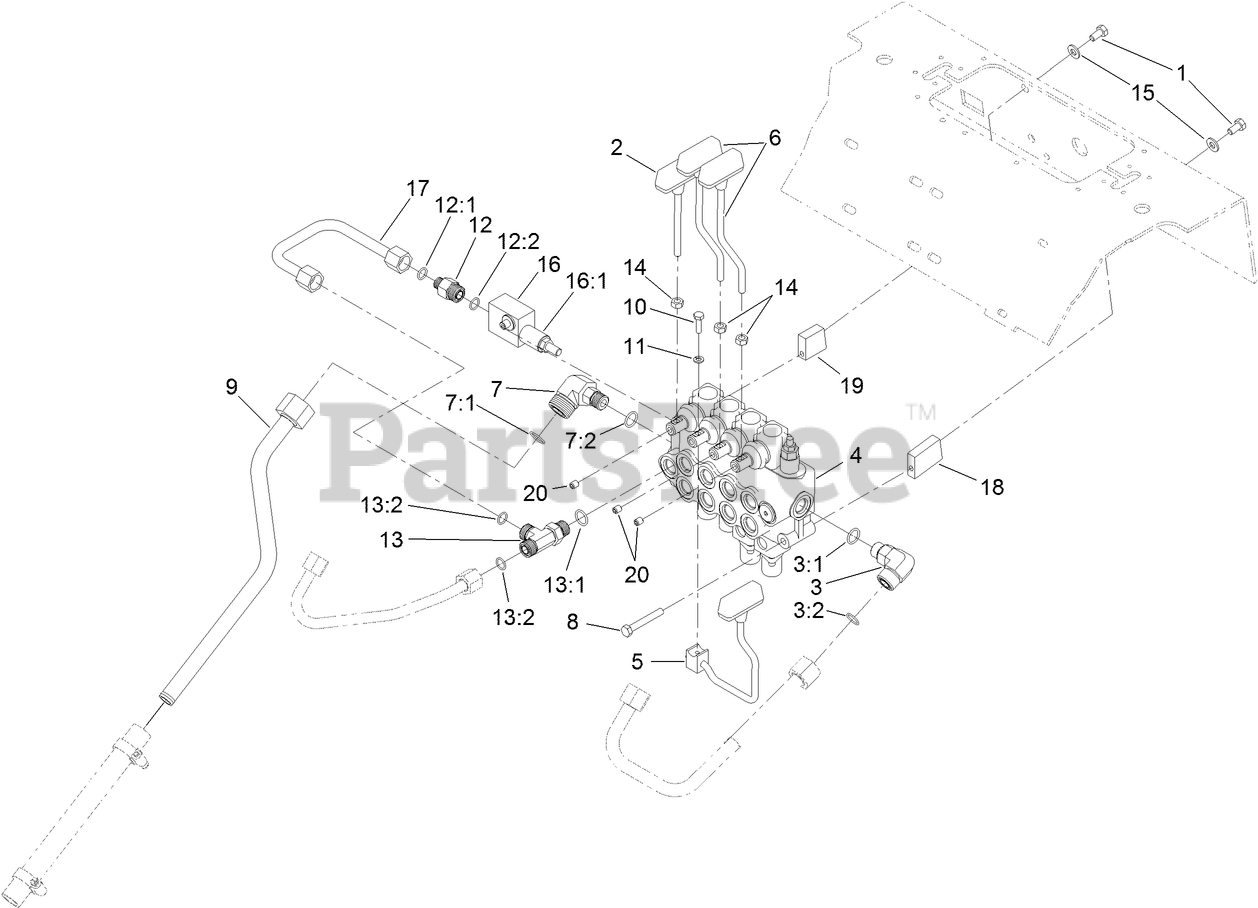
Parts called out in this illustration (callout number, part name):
1	SCREW-HH
2	LEVER-CYLINDER
3	FITTING-ELBOW, 90 DEG
3:1	O-RING
3:2	O-RING
4	HYD FOUR SPOOL VALVE ASM
5	LEVER-CONTROL
6	LEVER-DRIVE
7	FITTING-ELBOW, 90 DEG
7:1	O-RING
7:2	O-RING
8	SCREW-HH
9	TUBE-TANK, HYD
10	SCREW-HH
11	WASHER-LOCK
12	FITTING-STRAIGHT
12:1	O-RING
12:2	O-RING
13	FITTING-TEE
13:1	O-RING
13:2	O-RING
14	NUT-HEX
15	WASHER-PLAIN
16	RELIEF VALVE ASM
16:1	CARTRIDGE-VALVE, RELIEF
17	TUBE-HYD
18	SPACER V
19	SPACER-UPPER V
20	SCREW-SET, HSH
